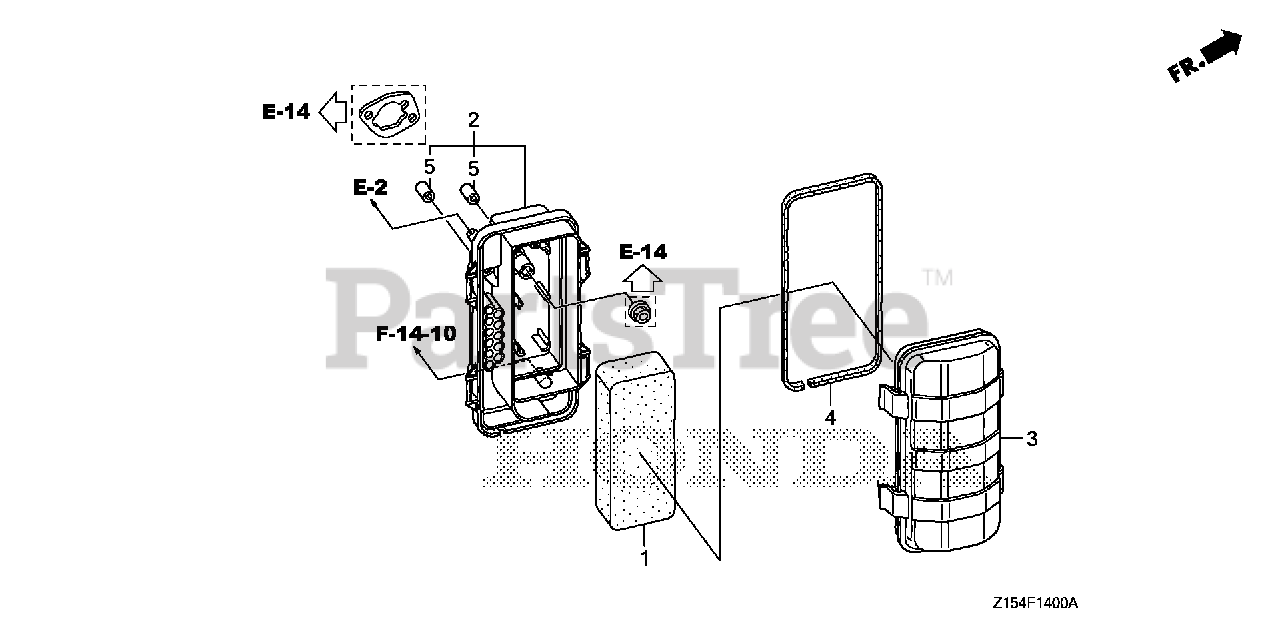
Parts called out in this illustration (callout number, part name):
1	ELEMENT, AIR CLEANER
2	HOUSING, AIR CLEANER
3	COVER, AIR CLEANER
4	SEAL, AIR CLEANER COVER
5	COLLAR, AIR CLEANER
